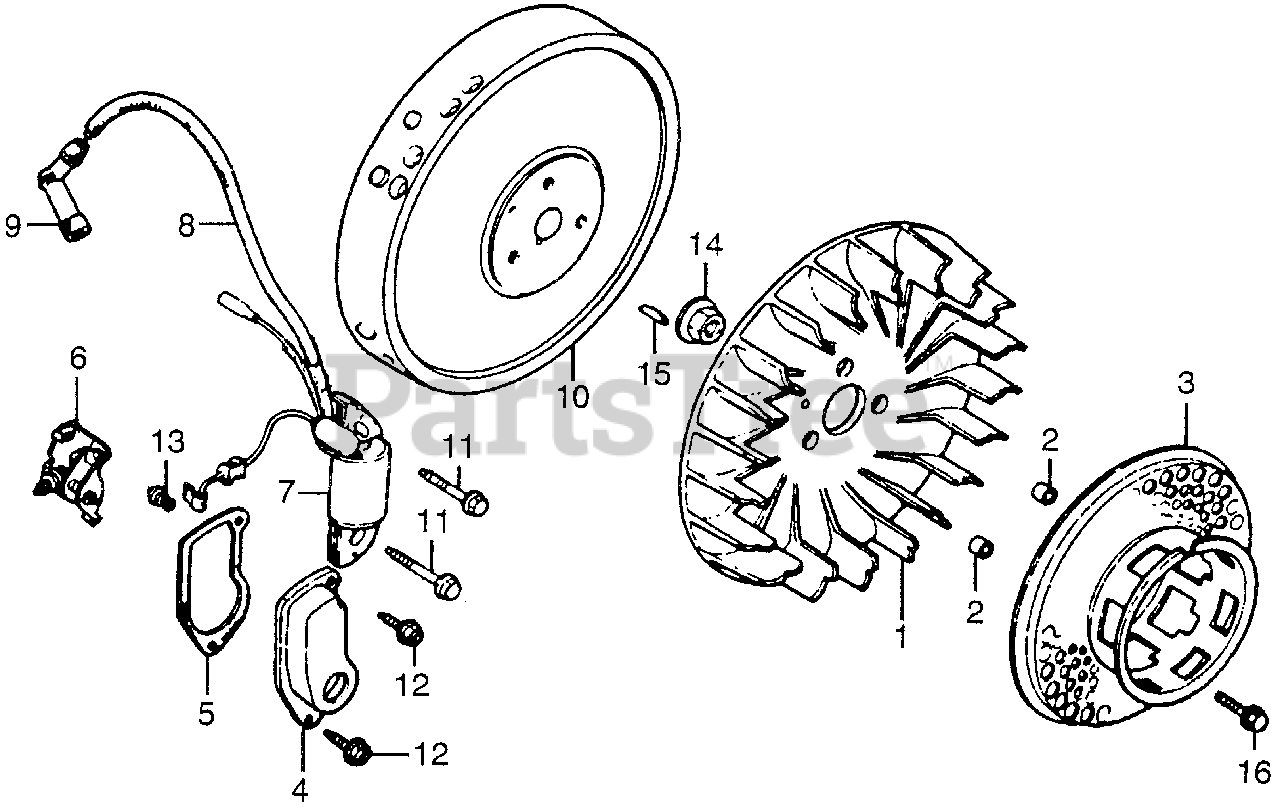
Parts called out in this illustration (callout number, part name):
1	FAN, COOLING
2	COLLAR, FAN
3	PULLEY, STARTER
4	COVER, POINTS
5	GASKET, POINT COVER
6	POINTS ASSY.
7	COIL ASSY., IGNITION
8	TUBE, IGNITION RUBBER
9	CAP ASSY., NOISE SUPPRESSOR
11	BOLT, FLANGE (6X32)
12	BOLT, FLANGE (5X10)
13	SCREW-WASHER (5X12)
14	NUT, SPECIAL (14MM)
15	KEY, SPECIAL WOODRUFF (25X18)
16	BOLT, FLANGE (6X16)
